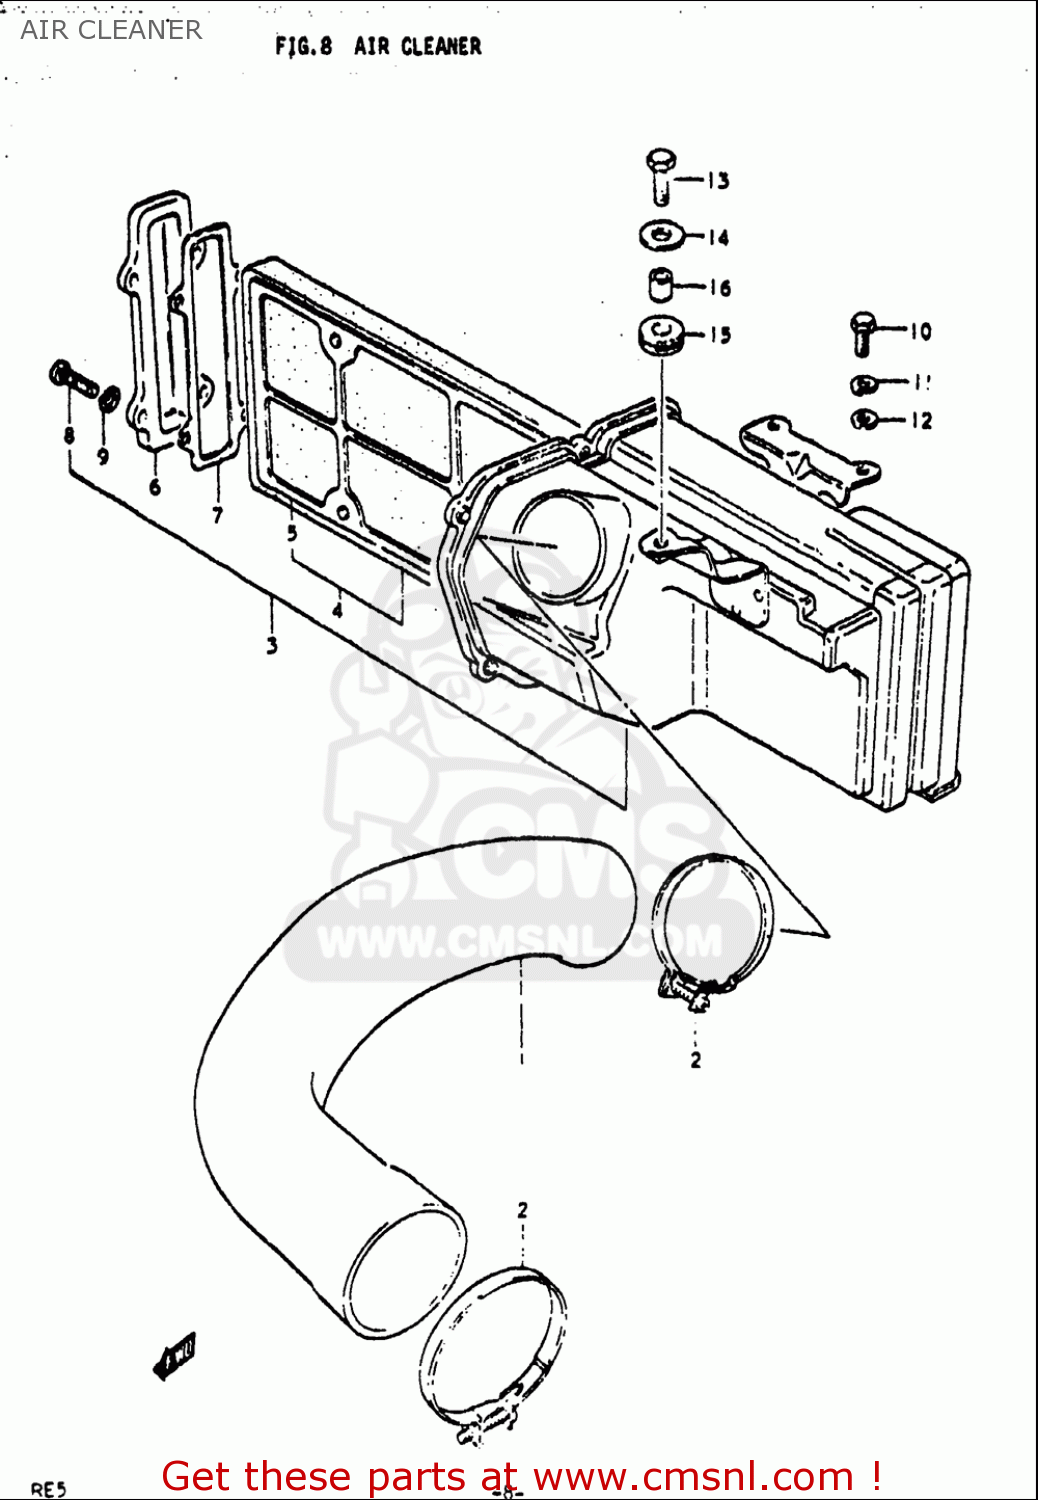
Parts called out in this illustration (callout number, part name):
2	CLAMP
5	ELEMENT,AIR CLEANER
8	SCREW
9	WASHER,LOCK
10	BOLT
11	WASHER,LOCK
12	WASHER
13	BOLT
14	WASHER(6.5X20X1.2)
15	CUSHION
16	SPACER,6.5X9X7
